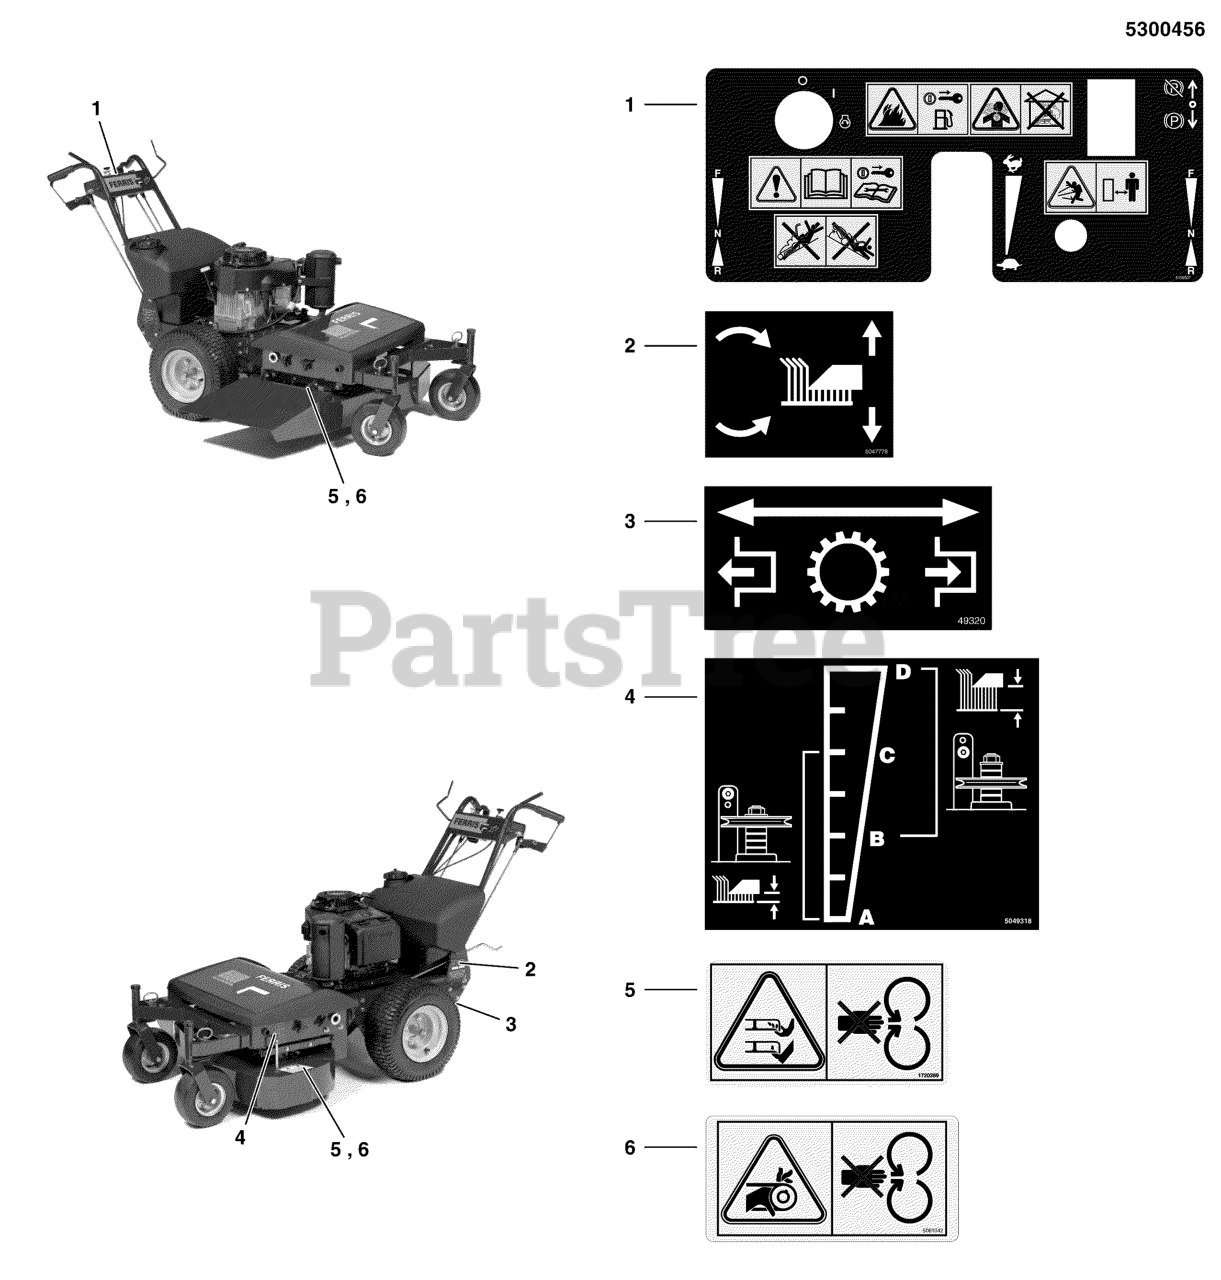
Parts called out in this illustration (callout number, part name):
1	DECAL, CONTROL PANEL HC/CE
2	DECAL-CUT HEIGHT ADJUST HYDRO CUT
3	DECAL, HYDRO RELEASE
4	DECAL, HEIGHT OF CUT
5	DECAL-DANGER ROTATING BLADE SYMBOLS
6	DECAL, CE DANGER
